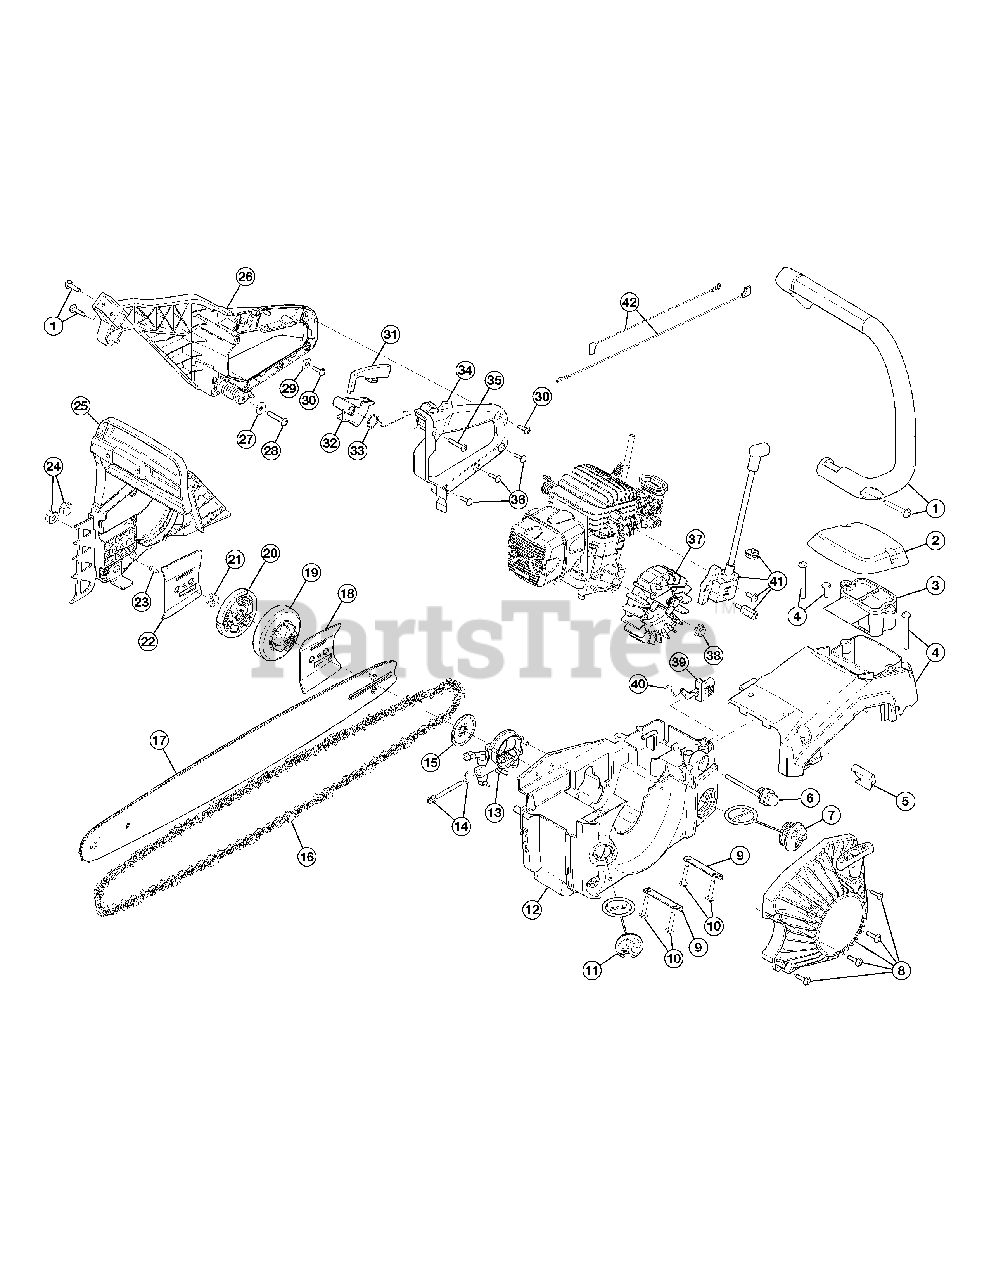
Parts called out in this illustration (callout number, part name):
1	Handle Assembly with Screws
2	Air Cleaner Cover Assembly
3	Air Cleaner Assembly
4	Top Cover Assembly
6	Primer Bulb Assembly
7	Fuel Cap
8	Starter Housing Assembly
9	Engine Mount Plate Assembly (Incl. 10)
10	Engine Mount Screw
11	Oil Cap
12	Housing Assembly (Incl. 6, 7 & 11)
13	Oil Pump Assembly
14	Tension Screw & Nut Assembly
15	Oil Pump Shield
16	18" Chain
17	Chain Guide Bar
18	Inner Guide Plate
19	Clutch Drum Assembly
20	Clutch
21	Clutch Nut
22	Outer Guide Plate
23	Guide Plate Screw
24	Chain Guide Bar Nut
25	Chain Brake Assembly
26	Rear Handle Assembly
27	Grip Anti-vibration Washer
28	Grip Anti-vibration Screw
29	Throttle Clamp Washer
30	Throttle Clamp Screw
31	Trigger Release
32	Throttle Trigger
33	Trigger Release Spring
34	Rear Handle Cover Assembly (with Switch)
35	Upper Grip Screw
36	Lower Grip Screw
37	Flywheel Assembly
38	Flywheel Nut
39	Choke Lever Assembly
40	Choke Rod
41	Module Assembly
42	Ground Wire
